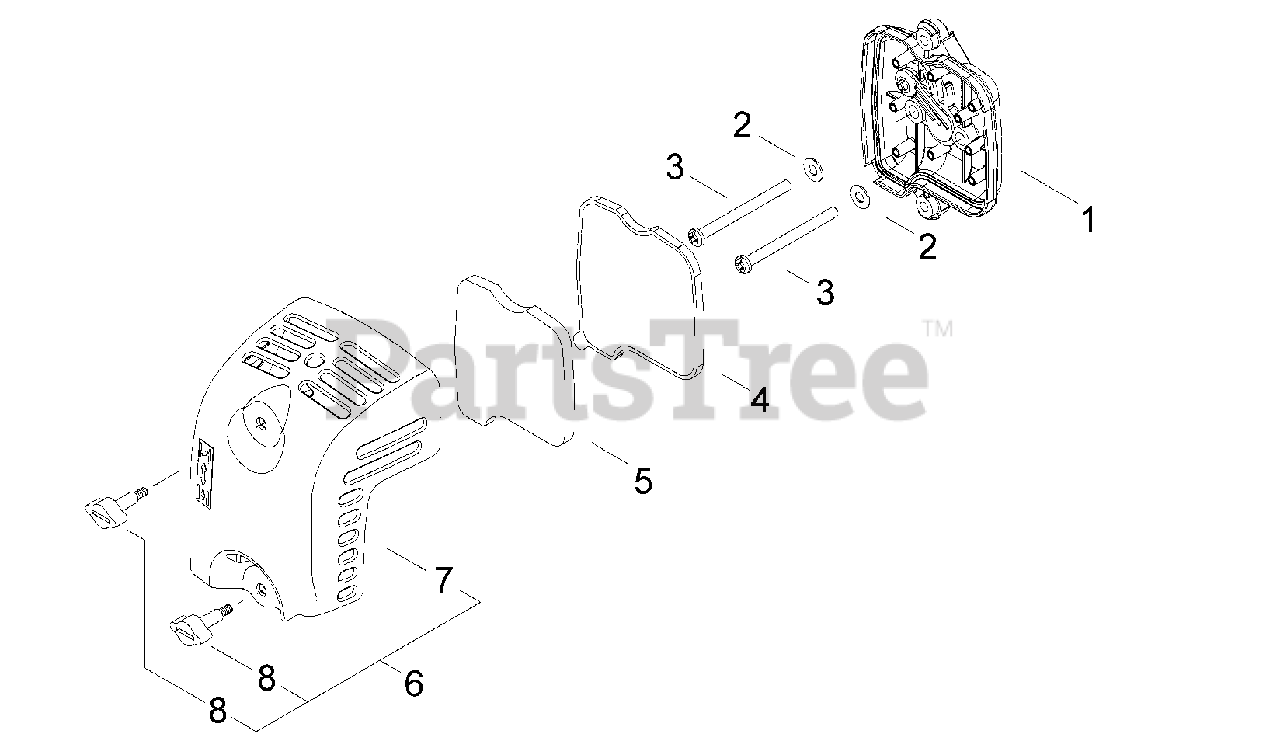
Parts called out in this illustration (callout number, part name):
1	AIR FILTER CASE ASSY
2	WASHER - 5
3	SCREW - 5X60
4	FILTER, AIR
5	PRE-FILTER - FOAM
6	AIR FILTER COVER ASSY
7	COVER, AIR FILTER
8	THUMBSCREW
